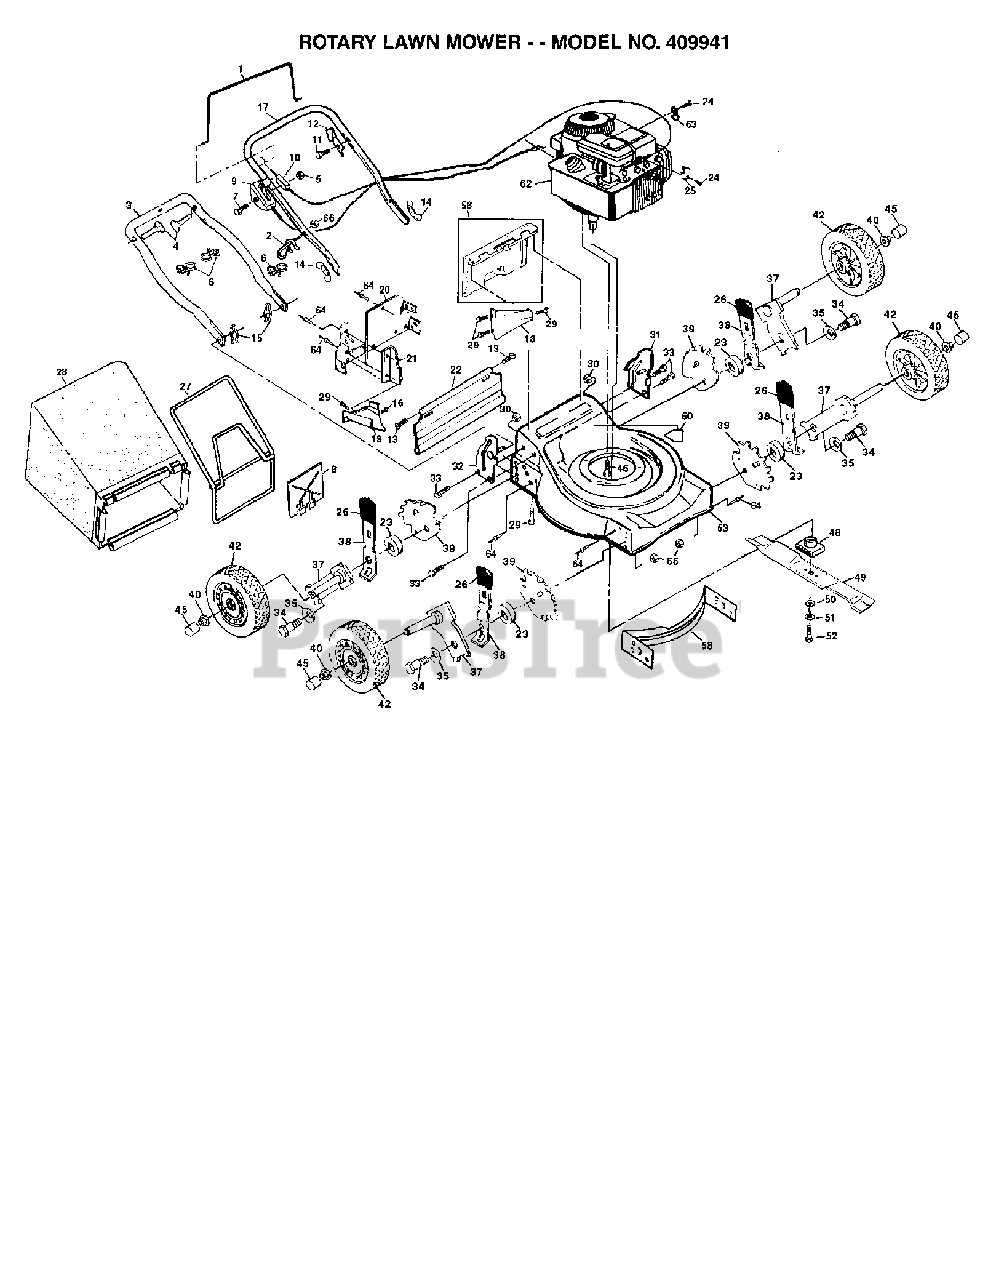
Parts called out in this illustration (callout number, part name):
1	CONTROL BAR
3	HANDLE.LOWER.STD.PNT.BLK
4	HANDL BOLT
7	MACHINE SCREW 1/4-20X2-1/4
8	Mulcher Plate
10	CABLE.MZR.51.RT.SP./PU.
11	TAPPING SCREW
12	BRACKET.UPSTOP
13	HINGE SCREW
14	NUT WING PM
15	HAIRPIN COTTER
16	SCREW.HXTAP.10-24
17	UPPER HANDLE
18	REAR BAFFLE
19	DISCHARGE BAFFLE
20	BACK PLATE
21	SIDE BAFFLE
22	REAR SKIRT
23	RP SPACER HT ADJ
24	SCREW.HEX.HEAD.WASHER.10-16
27	FRAME.CATCHER.2.5.BUSHEL
31	HANDLE BRACKET ASSEMBLY - LEFT
32	HANDLE BRACKET ASSEMBLY-RIGHT
33	SELF-TAPPING SCREW 5/16-18X3/4
35	WASHER.BELLEVILLE
37	ARM.AXLE.ASM.BZP
38	SELECTOR SPRING
39	WHEEL ADJUSTING BRACKET
40	HEX FLANGE LOCKNT
42	WHEEL.8X1.75.PR.SP.WHITE
46	BOLT 3/8-16X1-1/8
48	BLADE ADAPTOR
49	20" MULCHING BLADE
50	WASHER,HARDEN
52	SCREW, HEX HD 3/8-24 X 1-3/8
56	REAR DOOR ASSEMBLY KIT
58	Poulan TBD
60	DANGER DECAL
63	GUIDE CLIP PM
64	RIVET BLIND
66	NUT
